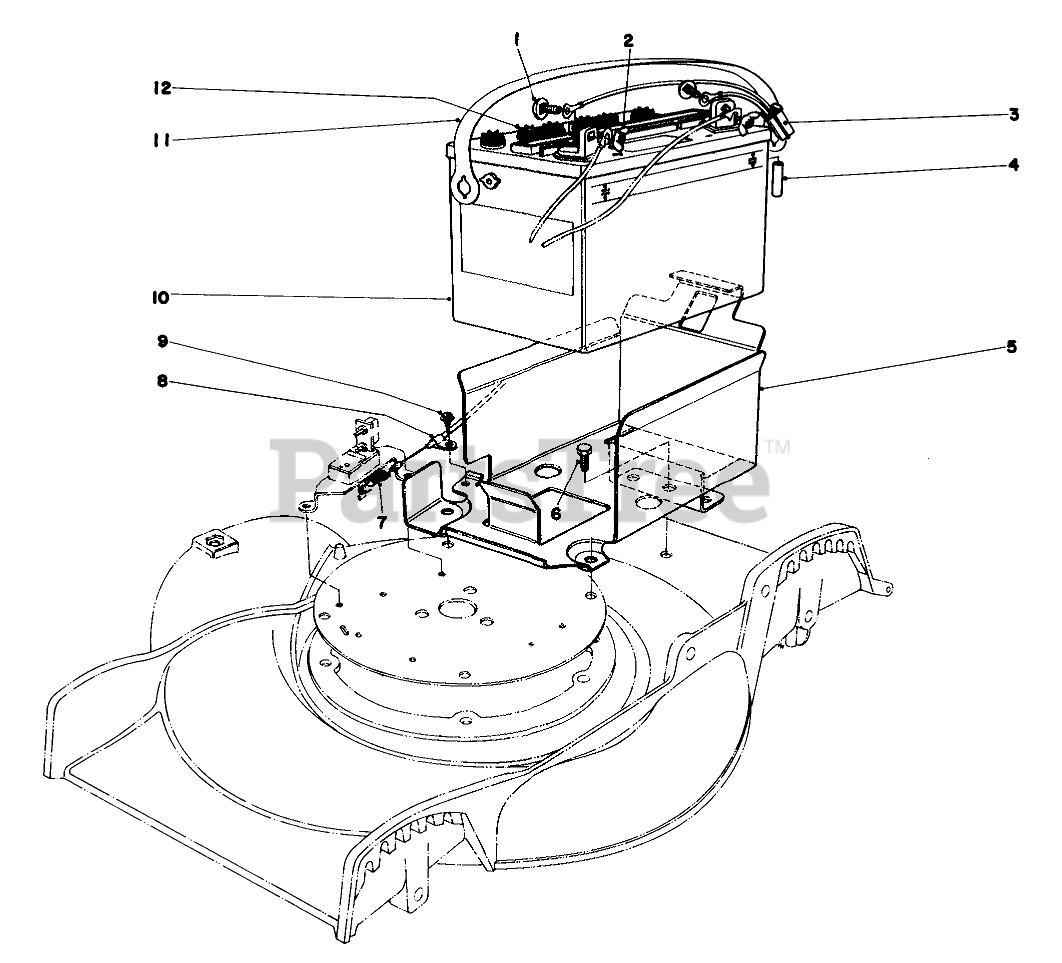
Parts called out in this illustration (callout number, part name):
1	Bolt-Carriage
2	NUT-WING
3	Battery Harness
4	Vent Tube
5	Battery Holder
6	SCREW-HWHTF
7	Control Cable Assembly
8	Clamp
9	SCREW-HWHTF
10	Battery (Incl. Ref. #1-3)
11	Carrying Strap
12	Vent Cap
